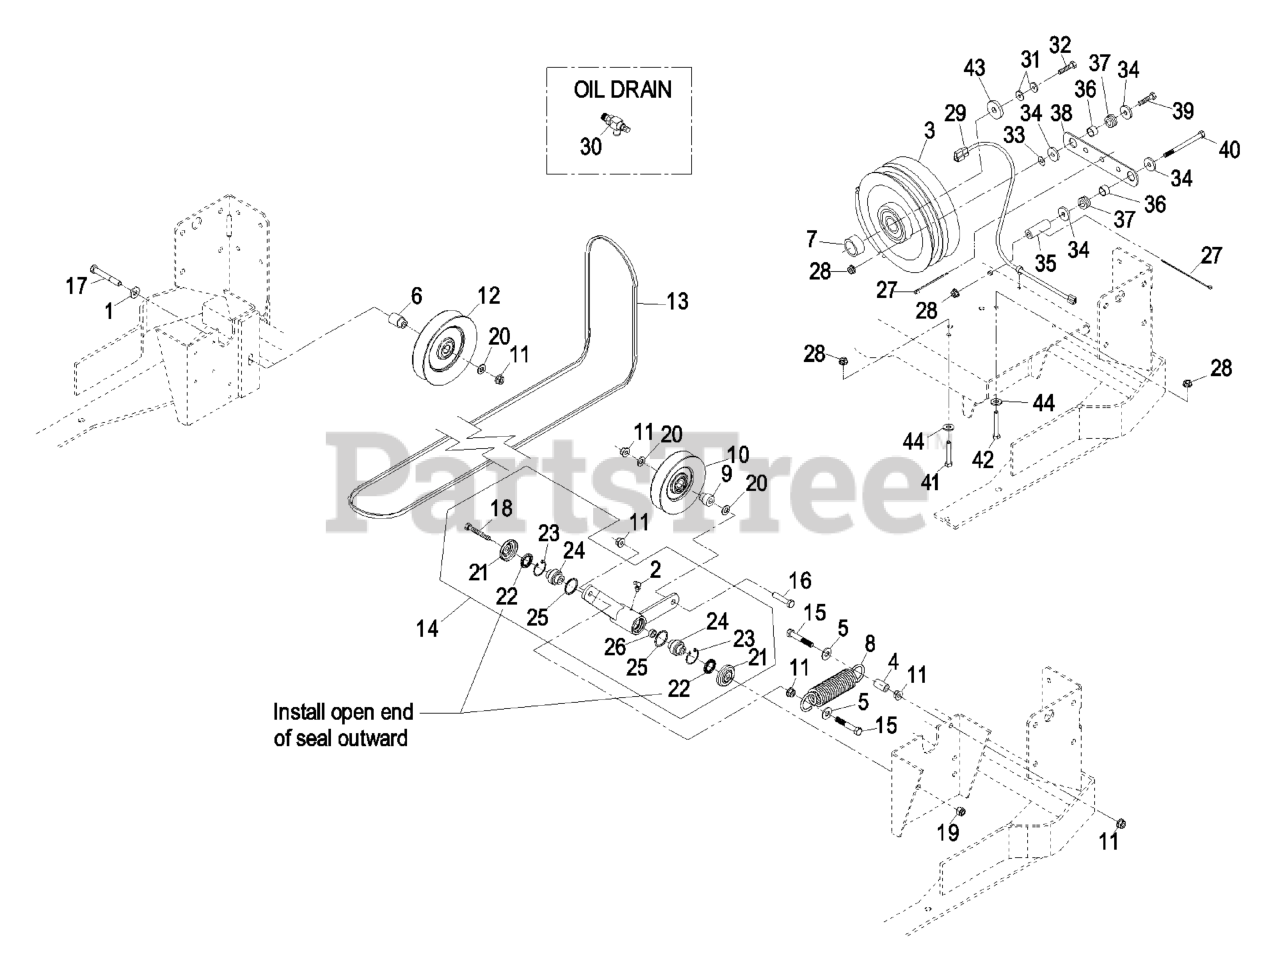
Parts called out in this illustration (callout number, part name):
1	WASHER-BELLEVILLE
2	FITTING-GREASE, 90 DEG
5	WASHER-FLAT
6	BUSHING-IDLER
8	SPRING-EXTENSION
9	BUSHING-IDLER
10	PULLEY-IDLER
11	NUT-HHF, WHIZ
12	PULLEY-IDLER
13	BELT-V B 118.75
14	KIT,MULE IDLER LZ
15	SCREW-HH
16	SCREW-HH
17	SCREW-HH
18	SCREW-HH
19	NUT-LOCK, NI
20	WASHER-FLAT
21	GUARD-TOP
22	SEAL-LIP, SINGLE
23	RING-SNAP
24	BEARING-SPHERICAL
27	TIE-PLASTIC
29	KIT,CLUTCH JUMPER HARNESS
30	VALVE-OIL DRAIN
31	WASHER-SPRING
32	SCREW-HH
33	WASHER-FLAT
35	SPACER-ANCHOR, CLUTCH
37	GROMMET
38	STRAP-CLUTCH, BRAKE
39	SCREW-HH
40	SCREW-HH
41	SCREW-HH
42	SCREW-HH
43	WASHER-CLUTCH
44	WASHER-SPRING
